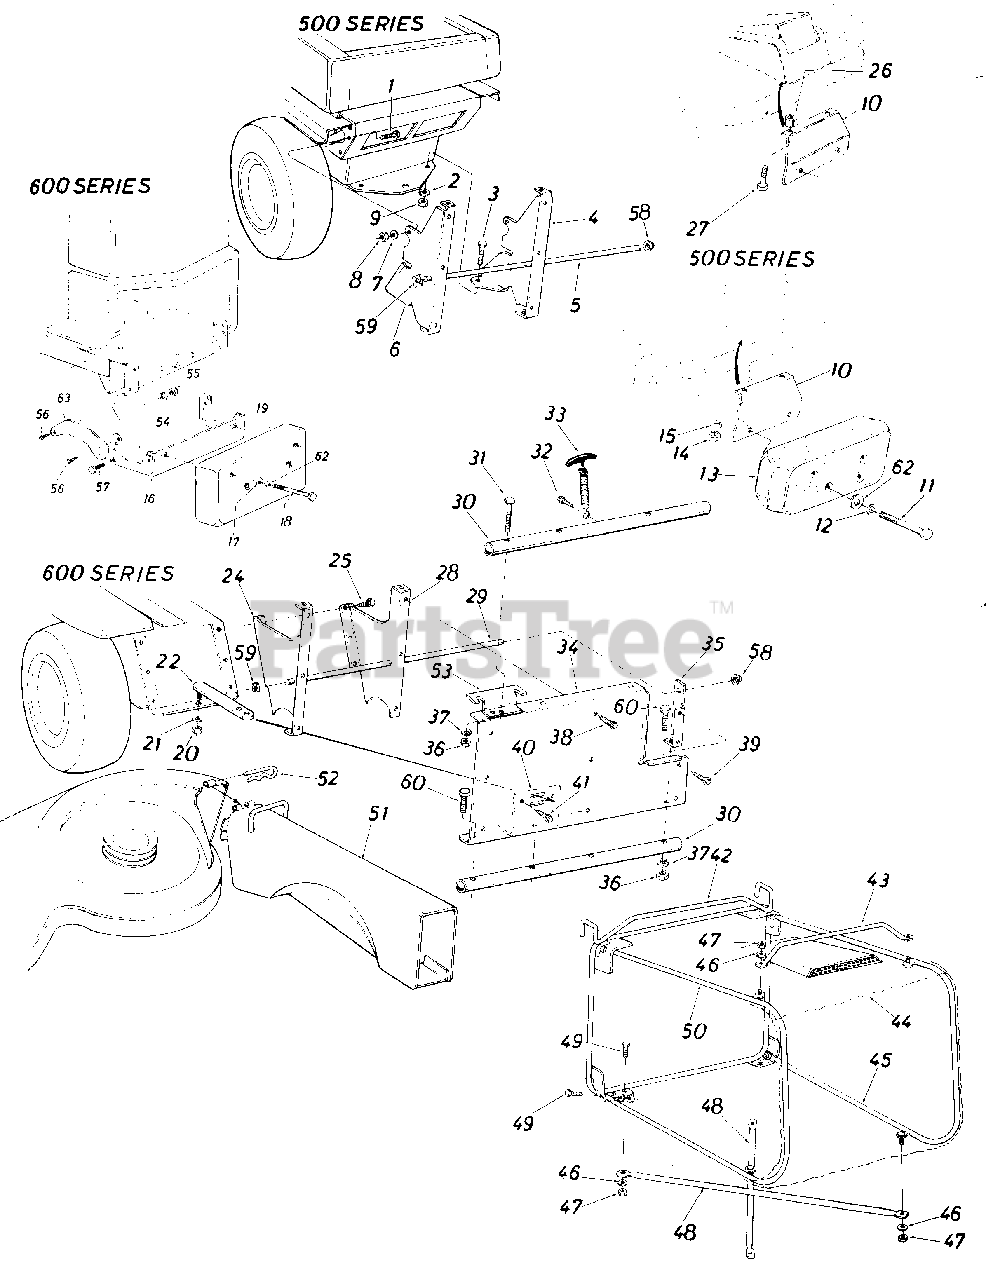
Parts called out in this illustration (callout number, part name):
1	Hex Bolt 5/16-18 x 1.0" Lg.*
2	L.-Wash. 5/16" I.D.*
3	Hex Bolt 5/16-18 x 1.00"
4	Catcher Support Brkt -R.H.
7	L-Wash. 5/16" I.D.*
8	Hex Nut 5/16-18 Thd.*
9	Hex Nut 5/16-18 Thd.*
10	Counterweight Bracket
11	Hex Bolt 3/8-16 x 4.5" Lg.*
12	Belleville Wash..400" I.D. x.88" O.D.
13	Front Counterweight 38lbs.
14	Hex Nut 5/16-18 Thd.*
15	L.-Wash. 5/16" I.D.*
16	Counterweight Bracket
17	Belleville Wash. .400" I.D. x.88" O.D.
18	Hex Bolt 3/8-16 x 4.5" Lg.*
19	Front Counterweight 38 Ibs.
20	Hex Jam Nut 1/2-13 Thd.*
21	L.-Wash. 1/2" I.D.*
25	Hex Wash. Hd. Self Tap Scr. 5/16-18 x .75 Lg.*
26	Spacer .380" I.D. x 1.00" O.D. x .320" Lg.
27	Not Part of Kit
28	Catcher Support Brk't.-R.H.
31	Curved Carriage Bolt 5/16-18 x 1.75" Lg.
32	Hex "AB"-Tap Scr. 1/4 x .62" Lg.
33	Hood Latch Ass'y.
34	Grass Catcher Adapter
35	Grass Catcher Support Brk t. - R.H.
36	Hex Nut 5/16-18 Thd.*
37	L.-Wash. 5/16" I.D.*
38	Hex Wash. Hd. Self Tap Scr. 1/4-20 x .50" Lg.
39	Hex Wash. Hd. Self Tap Scr. 1/4-20 x . 50" Lg.
40	Hitch Bracket
41	Hex Wash. Hd. Self Tap Scr. 1/4-20 x .50" Lg.
42	Grass Bag Frame Ass'y.
43	Grass Catcher Handle 26.75
44	Grass Catcher Bag
47	Hex L.-Nut 1/4-20 Thd.
48	Bottom Cross Brace 30.36" Lg.*
49	Hex Bolt 1/4-20 x .62" Lg.*
52	Not Part of Kit
53	Grass Catcher Support Plate
54	L.-Wash. 7/16" I.D.*
55	Hex Nut 7/16-20 Thd.*
56	Hex AB Tap Scr. 5/16-18 x 1" Lg.
57	Hex Bolt 7/16-20 x 1.00" Lg.*
58	Push Cap
59	Speed Nut
60	Hex Bolt 5/16-18 x 1.75" Lg.*
62	Fl.-Wash. .390" I.D. x 1.12" O.D. x .187 Thk.
63	Tie Strap
